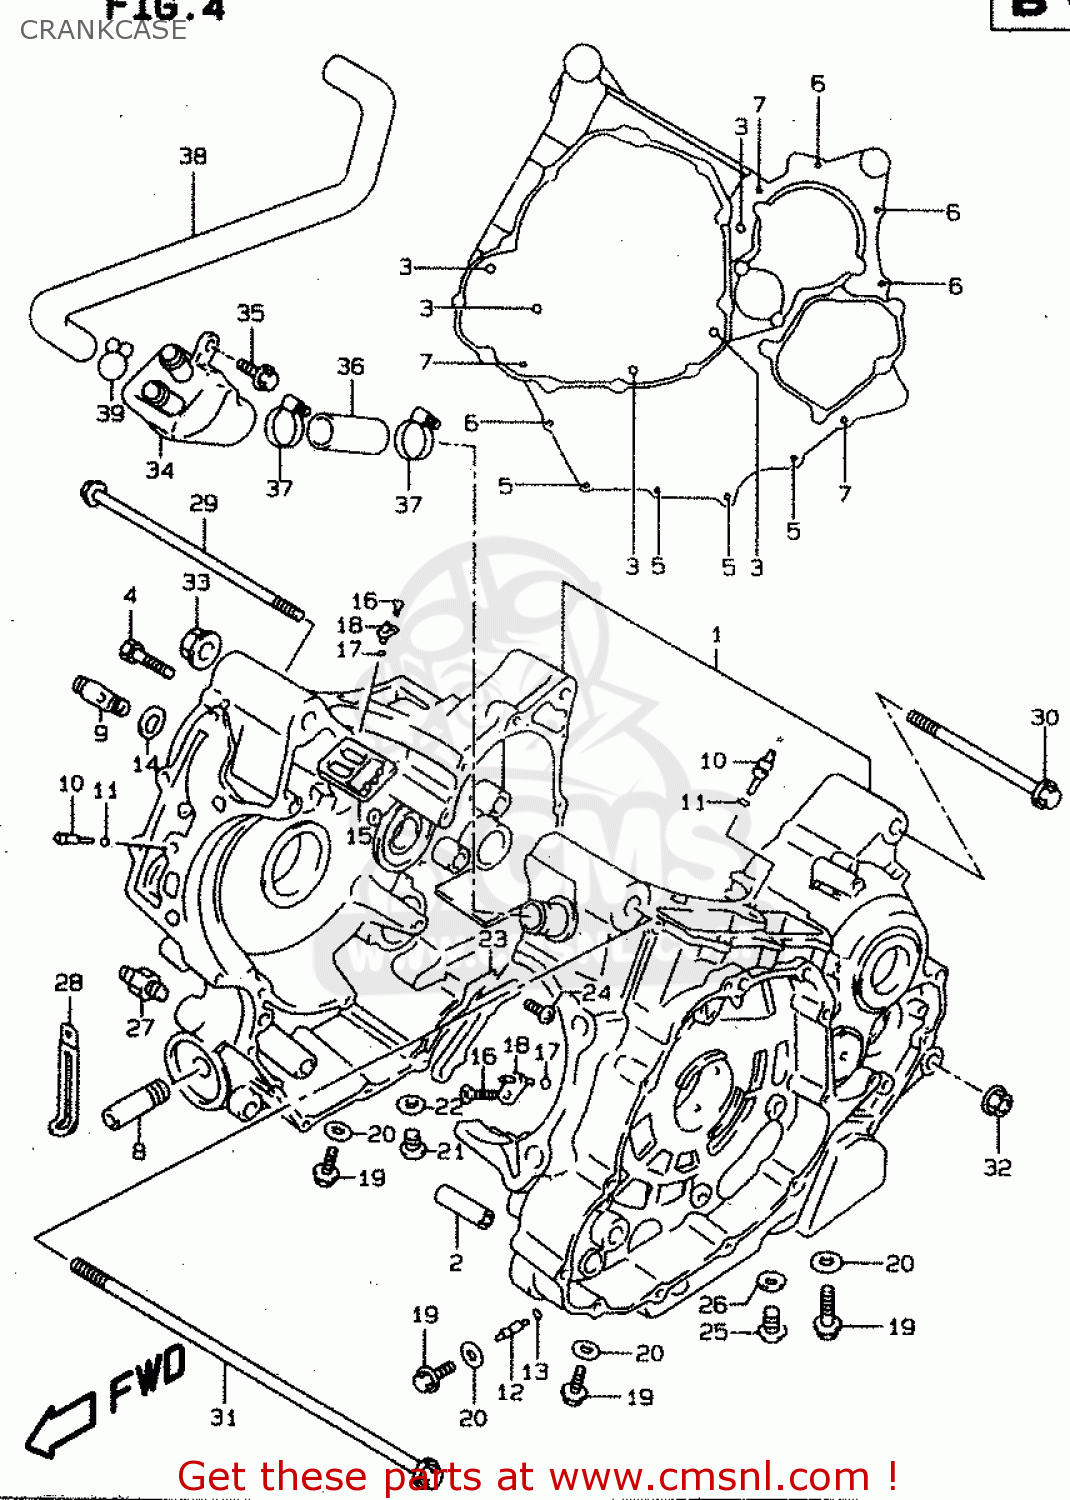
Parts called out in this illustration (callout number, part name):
1	CRANKCASE SET
2	PIN,CRANKCASE
3	BOLT
4	BOLT
5	BOLT
6	BOLT
7	BOLT
8	UNION,OIL STAND
9	JET,OIL GALLERY(3.6)
10	JET,OIL GALLERY
11	O RING(D:1.2,ID:4)
12	JET,AIR(14)
13	O RING(D:1.2,ID:4)
14	O RING(D:1.9,ID:12.6)
15	VALVE ASSY,BREATHER
16	SCREW(6X12)
17	O RING(D:1.2,ID:4)
18	JET,PISTON COOLING
19	BOLT
20	GASKET(8.2X14X1).6 (NAS)
21	PLUG
22	GASKET(16X22X2) (NAS)
23	COVER,OIL GALLERY
24	SCREW
25	PLUG
26	GASKET(13.8X18.8X4.8) (NAS)
27	SWITCH ASSEMBLY,OIL PRESSURE
28	CLAMP(L:65)
29	BOLT(10X205)
30	BOLT(10X155)
31	BOLT(12X340)
32	NUT
33	NUT 12MM
34	TANK,OIL RETURN
35	BOLT
36	HOSE,OIL RETURN
37	CLAMP
38	HOSE,BREATHER
39	CLIP
